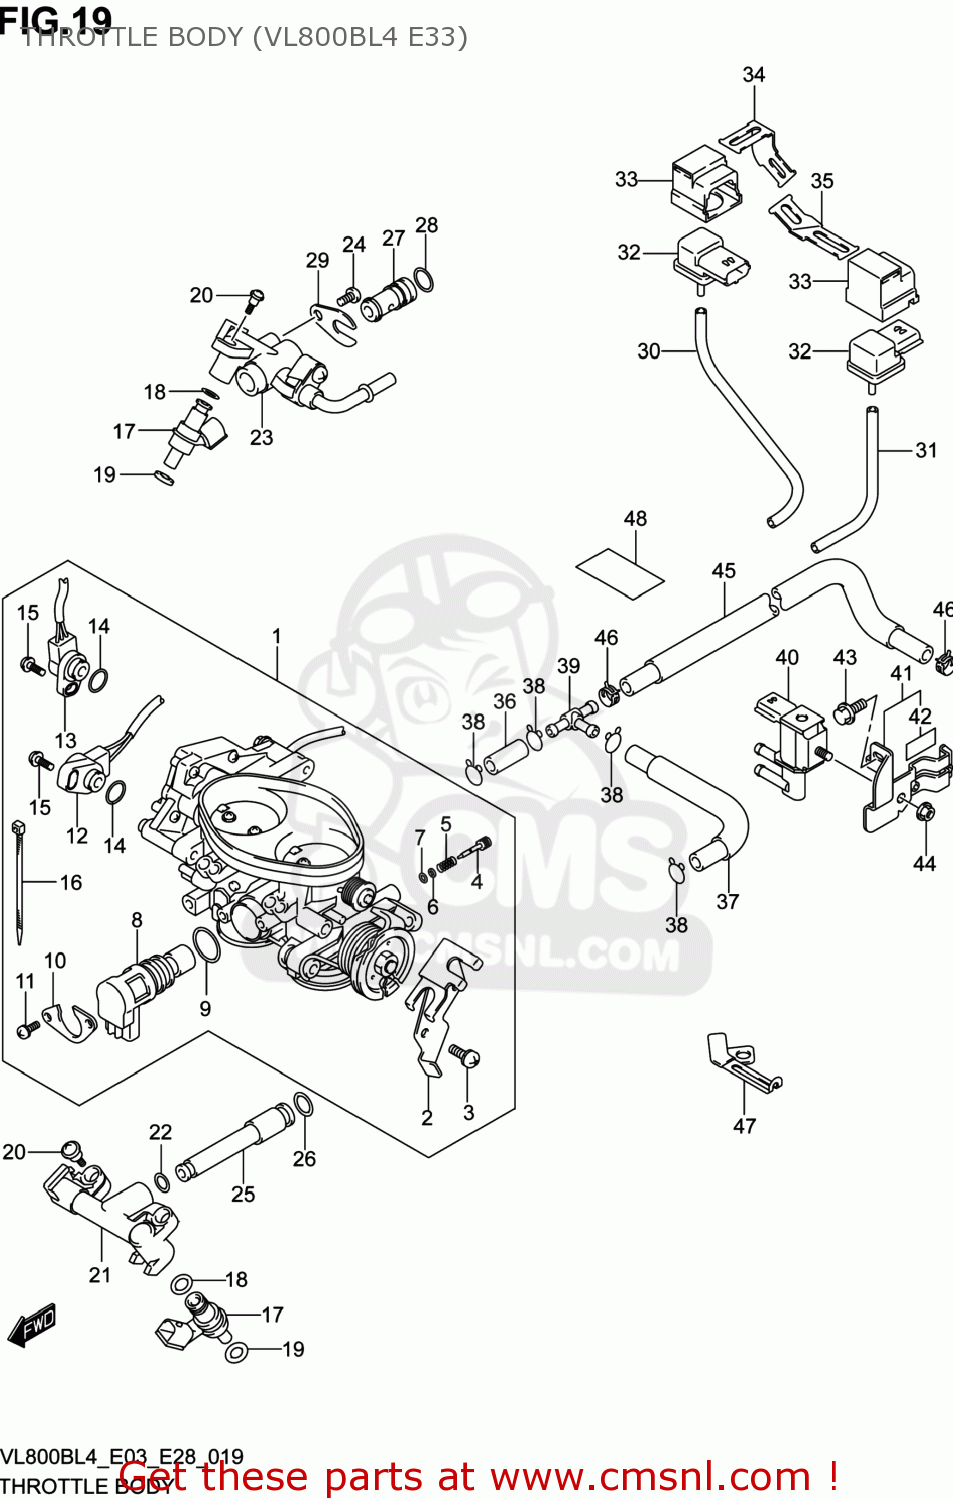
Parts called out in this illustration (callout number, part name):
1	BODY ASSY,THROTTLE
2	PLATE,STAY
3	SCREW
4	SCREW,AIR ADJUST
5	SPRING
6	WASHER
7	O RING
8	VALVE ASSY,ISC
9	O RING
10	PLATE,ISC VALVE
11	SCREW
12	SENSOR ASSY,THROTTLE NO.1
13	SENSOR ASSY,THROTTLE SUB
14	O RING
15	SCREW
16	CLAMP(L:145)
17	INJECTOR ASSY
18	O RING
19	RING,SEAL
20	SCREW,THROTTLE COVER
21	PIPE SET,FUEL FR
22	O RING
23	PIPE SET,FUEL RR
24	SCREW
25	JOINT
26	O RING
27	PLUG,STRAIGHT
28	O RING
29	PLATE,STAY
30	HOSE
31	HOSE
32	SENSOR,PRESSURE
33	HOLDER,SENSOR
34	BRACKET,BOOST SENSOR FR
35	BRACKET,BOOST SENSOR RR
36	TUBE,RUBBER
37	TUBE,RUBBER
38	CLIP
39	NIPPLE
40	VALVE ASSY,DUTY FOR PURGE
41	BRACKET,PURGE VALVE
42	CUSHION
43	BOLT
44	NUT
45	HOSE,CANISTER PURGE
46	CLIP
47	CLAMP,EVAPORATOR HOSE
48	TAPE,WIRING HARNESS(28X50X0.13
